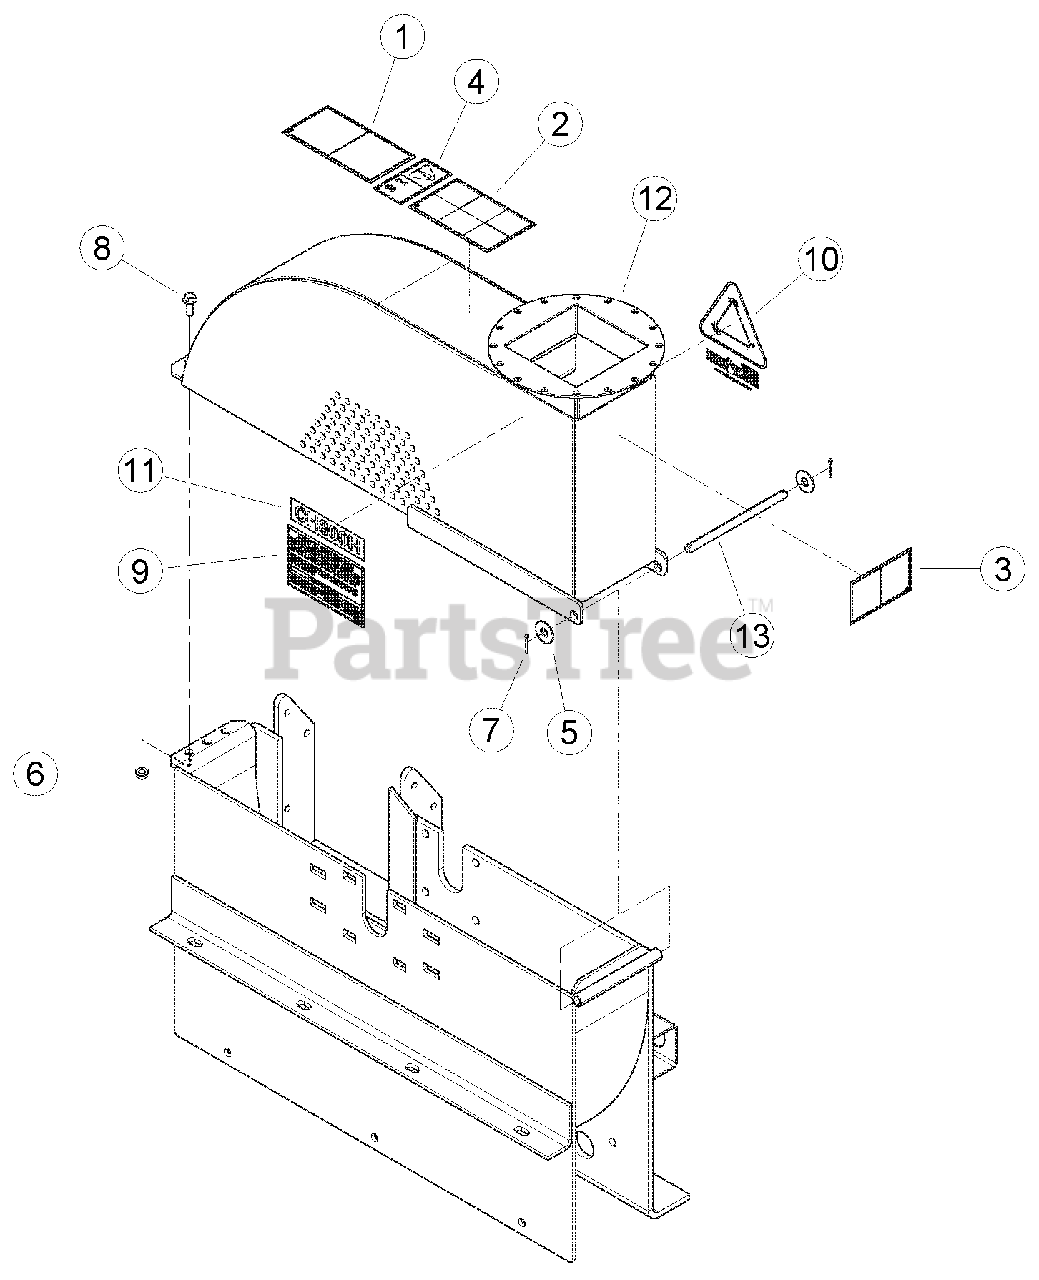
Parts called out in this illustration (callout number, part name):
1	DECAL, KNIFE ACCESS ISO
2	DECAL, OPERATING INSTRUCTIONS ISO
3	DECAL, DISCHARGE ISO
4	DECAL, MAINTENANCE ISO
5	WASHER, 1/2 FLAT ZP
6	NUT, 3/8 SERR FLANGE NC ZP
7	PIN, 1/8 X 1.00 COTTER ZP
8	BOLT, 3/8 X 1 SERR FLANGE GR5 NC ZP
9	DECAL, FLOW RATE HYDRAULIC
10	DECAL, CHIP IT
11	DECAL, MODEL CH800H
12	WELDMENT, TOP CHIPPER HOUSING
13	SHAFT, CHIPPER TOP PIVOT
